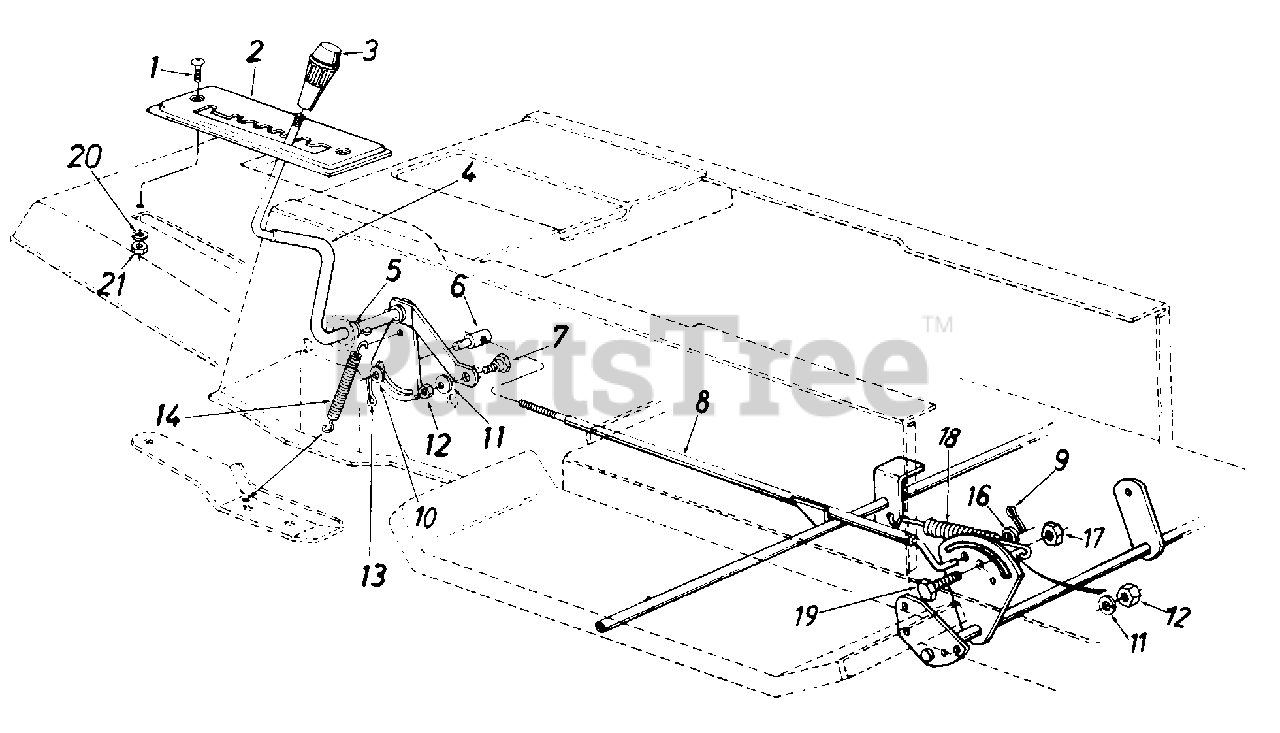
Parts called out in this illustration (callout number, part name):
1	Truss Mach. Scr. 1/4-20 x .75" Lg.
4	Speed Selector Cam Ass'y.
5	Flat Washer .53" I.D. x .93"
6	Ferrule 3/8-24 x .37" Dia.
7	Shoulder Bolt
8	Speed Control Rod Ass'y.
9	Cotter Pin 3/32" Dia. x .75"
10	Fl-Wash. .385" I.D. x .62"
11	L-Wash. 5/16" I.D.
12	Hex Nut 5/16-18 Thd.
13	Cotter Pin 3/32 Dia. x .75"
14	Spring
16	Fl-Wash. .47" I.D. x .88" O.D.
17	Hex L-Nut 5/16-18 Thd.
18	Ext. Spring 4.75" Lg.
19	Hex Cap Bolt 5/16-18 x 1" Lg. (Grade 5)
20	L-Wash. 1/4" I.D.
21	Hex Nut 1/4-20 Thd.
